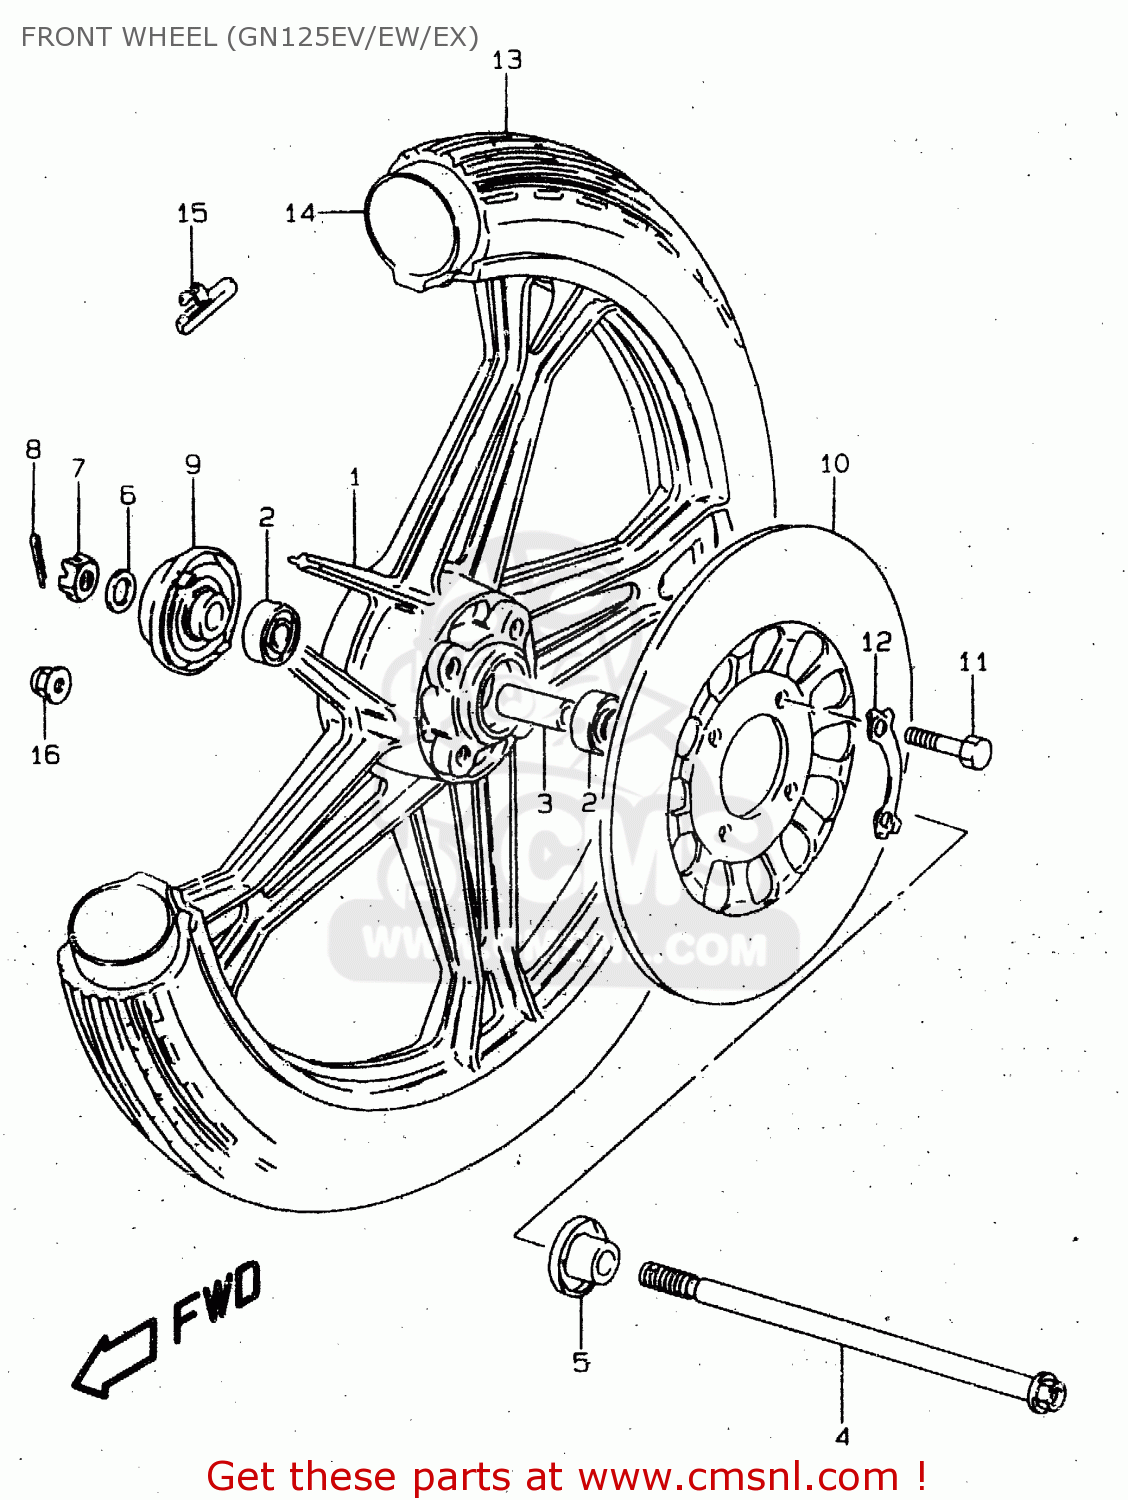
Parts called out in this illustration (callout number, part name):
1	WHEEL,FR(1.60X18)
2	BEARING
3	SPACER(12.5X19X52)
4	AXLE,FR
5	SPACER,FR AXLE,L
6	WASHER
7	NUT
8	COTTER PIN
9	BOX ASSY,SPEEDOMETER GEAR
10	DISC,FR BRAKE
11	BOLT(8X25)
12	WASHER
13	TIRE,FR(2.75-18)
14	TUBE,INNER
15	BALANCER,WHEEL NO.3.10
16	NUT 12MM
